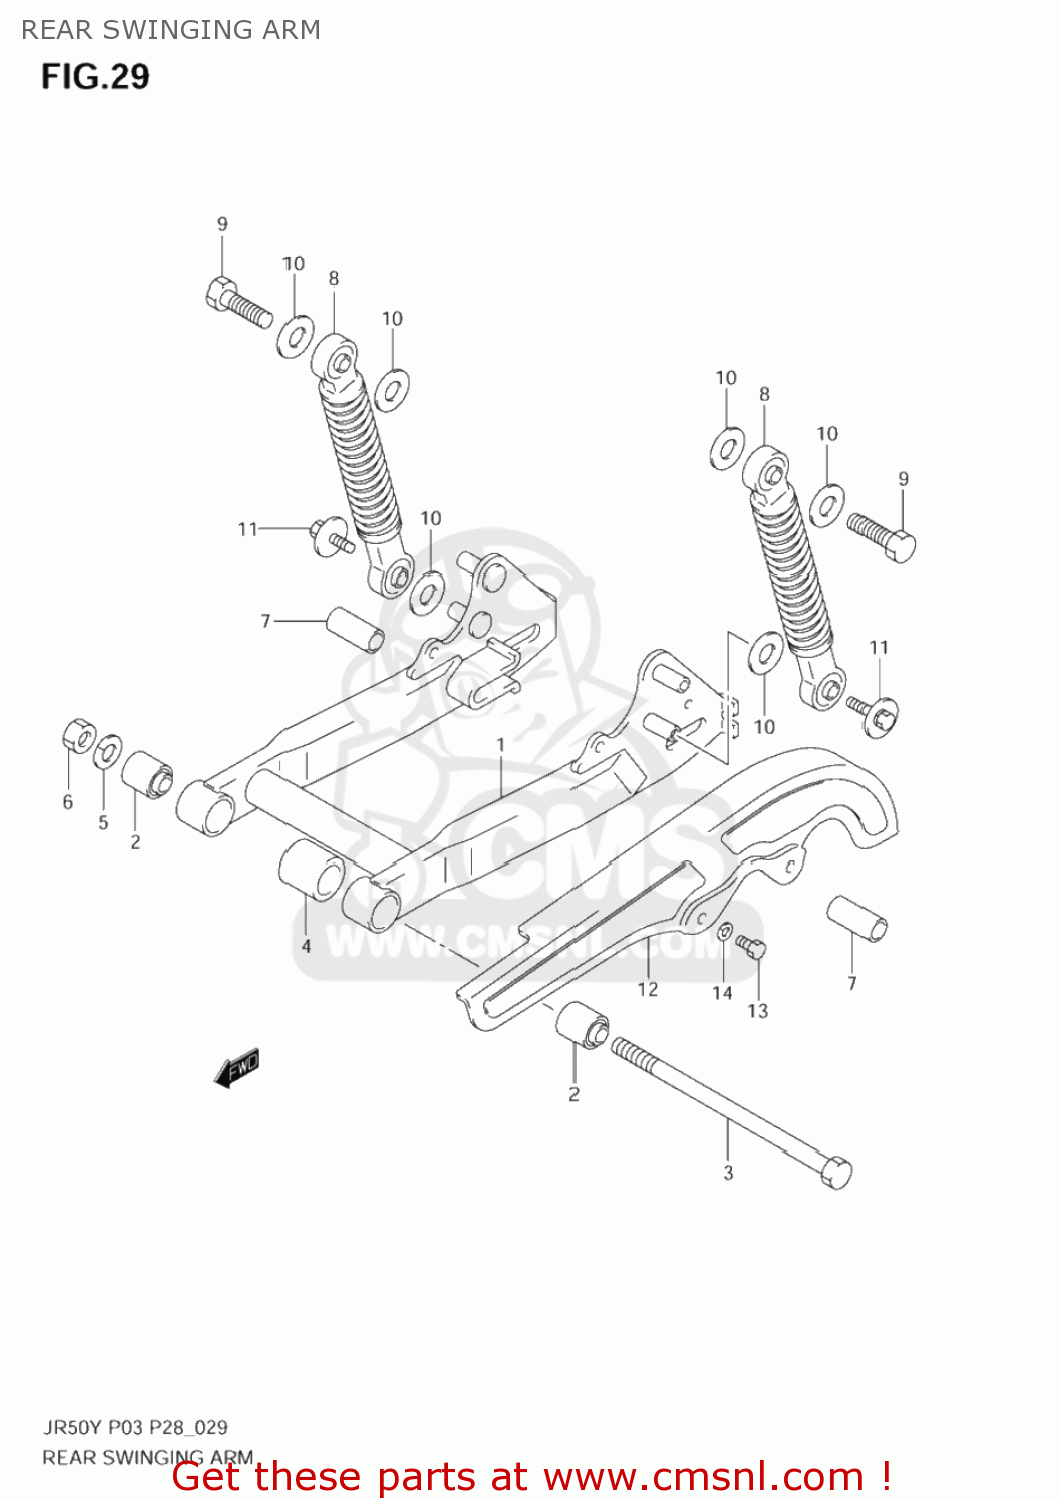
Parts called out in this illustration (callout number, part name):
1	SWINGINGARM ASSY,RR
2	BUSH
3	SHAFT,RR SWINGINGARM PIVOT
4	CUSHION
5	WASHER(10.5X22X1.6)
6	NUT
7	CAP,RR SHOCK ABSORBER BOSS
8	ABSORBER ASSY,RR SHOCK
9	BOLT
10	WASHER(10.5X22X1.6)
11	BOLT(6X12)
12	CASE,CHAIN
13	BOLT
14	LOCK WASHER
